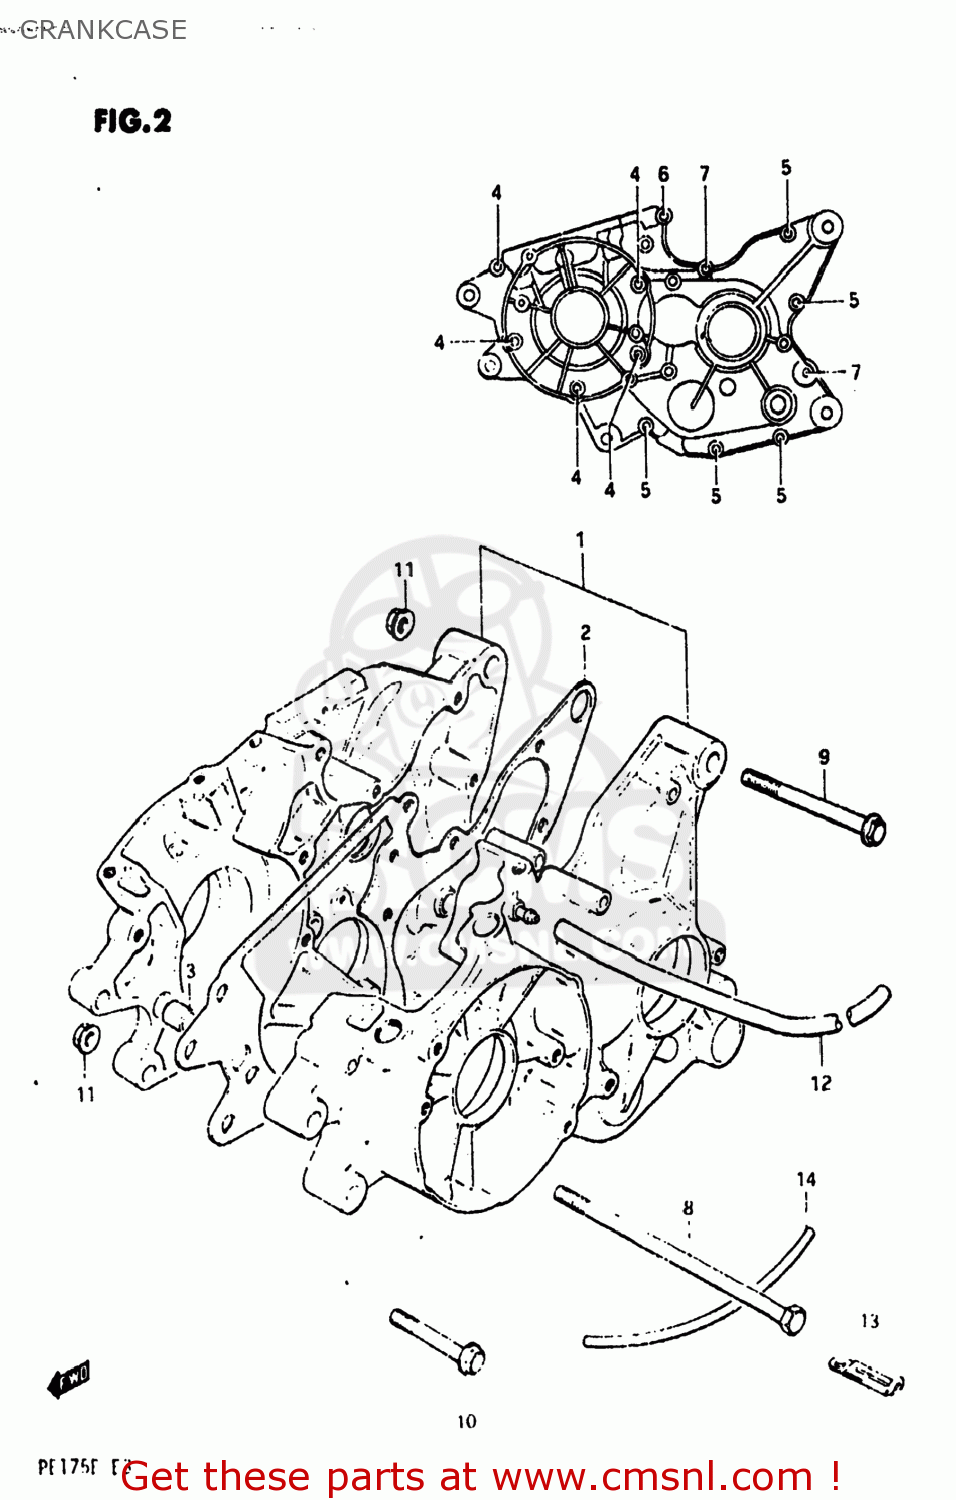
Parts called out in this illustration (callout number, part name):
1	CRANKCASE SET
2	GASKET,CRANKCASE
3	PIN
4	SCREW (6X45)
5	SCREW
6	SCREW
7	SCREW 6X60
8	BOLT 8X175
9	BOLT (8X95)
10	BOLT 8X65
11	NUT
12	HOSE,FUEL
13	CLAMP
14	HOSE
